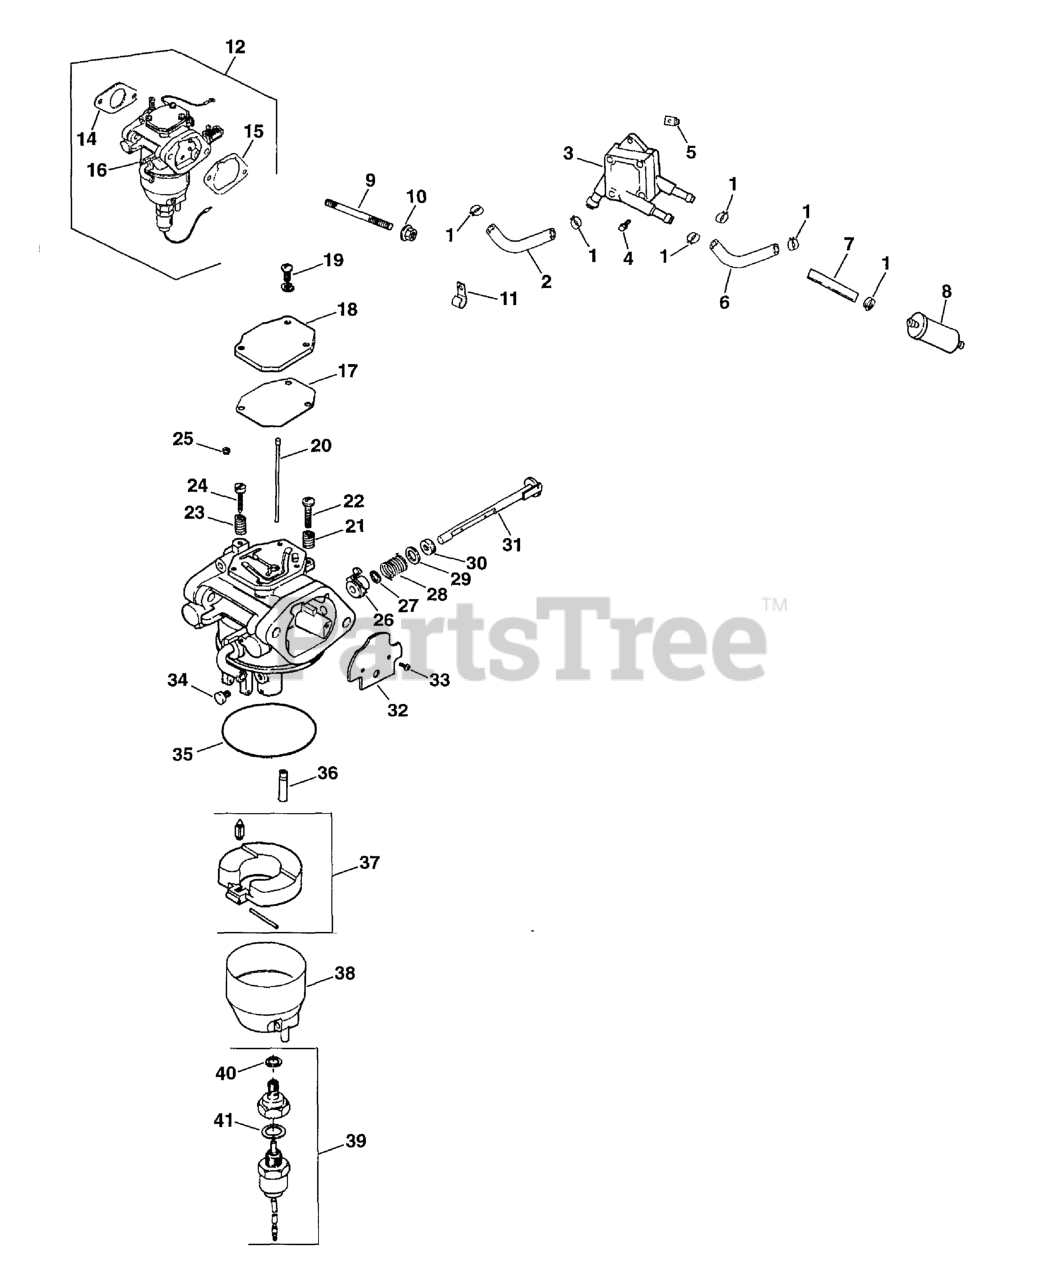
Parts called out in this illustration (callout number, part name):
1	CLAMP, HOSE 1/2" USE 25 237 14-S
2	LINE - (#DSC)
3	PUMP, FUEL - PULSE - USE 24 393 16
4	SCREW, TAP M6X1.7X18
5	NUT, PLASTIC (KM)-USE 25 100 37-S
6	LINE, FLEXIBLE FUEL 10.92"-USE 24 353 12
9	Stud, M6x1.0x128
10	NUT - USE M-641060
11	CLIP, CABLE
12	CARBURETOR - USE 24 853 17
12	KIT, CARBURETOR W/GASKET
14	GASKET, CARBURETOR
15	GASKET, AIR CLEANER BASE
17	KIT - USE 24 757 20
18	COVER, PASSAGE - DISCONTINUED
19	SCREW DISCONTINUED
20	JET, SLOW - DISCONTINUED
21	KIT - USE 24 757 18
22	SCREW, IDLE ADJUST - USE 24 757 18
23	SPRING, THROTTLE - DISC
24	KIT - USE 24 757 18
25	JET, AIR BLEED - DISC.
27	RING, CHOKE LEVER-USE 24 757 19-S
29	COLLAR, CHOKE-USE 24 757 19-S
30	WASHER-USE 24 757 19-S
31	SHAFT, CHOKE-USE 24 757 19-S
32	PLATE, CHOKE-USE 24 757 19-S
33	SCREW - DISCONTINUED
34	JET, MAIN - DISCONTINUED
35	KIT - USE 24 757 20
36	NOZZLE DISCONTINUED
37	KIT - USE 24 757 18
38	CHAMBER, FLOAT
39	KIT - USE 24 757 22
40	DISC. SEE PARTS BULLETIN
41	KIT - USE 24 755 15
